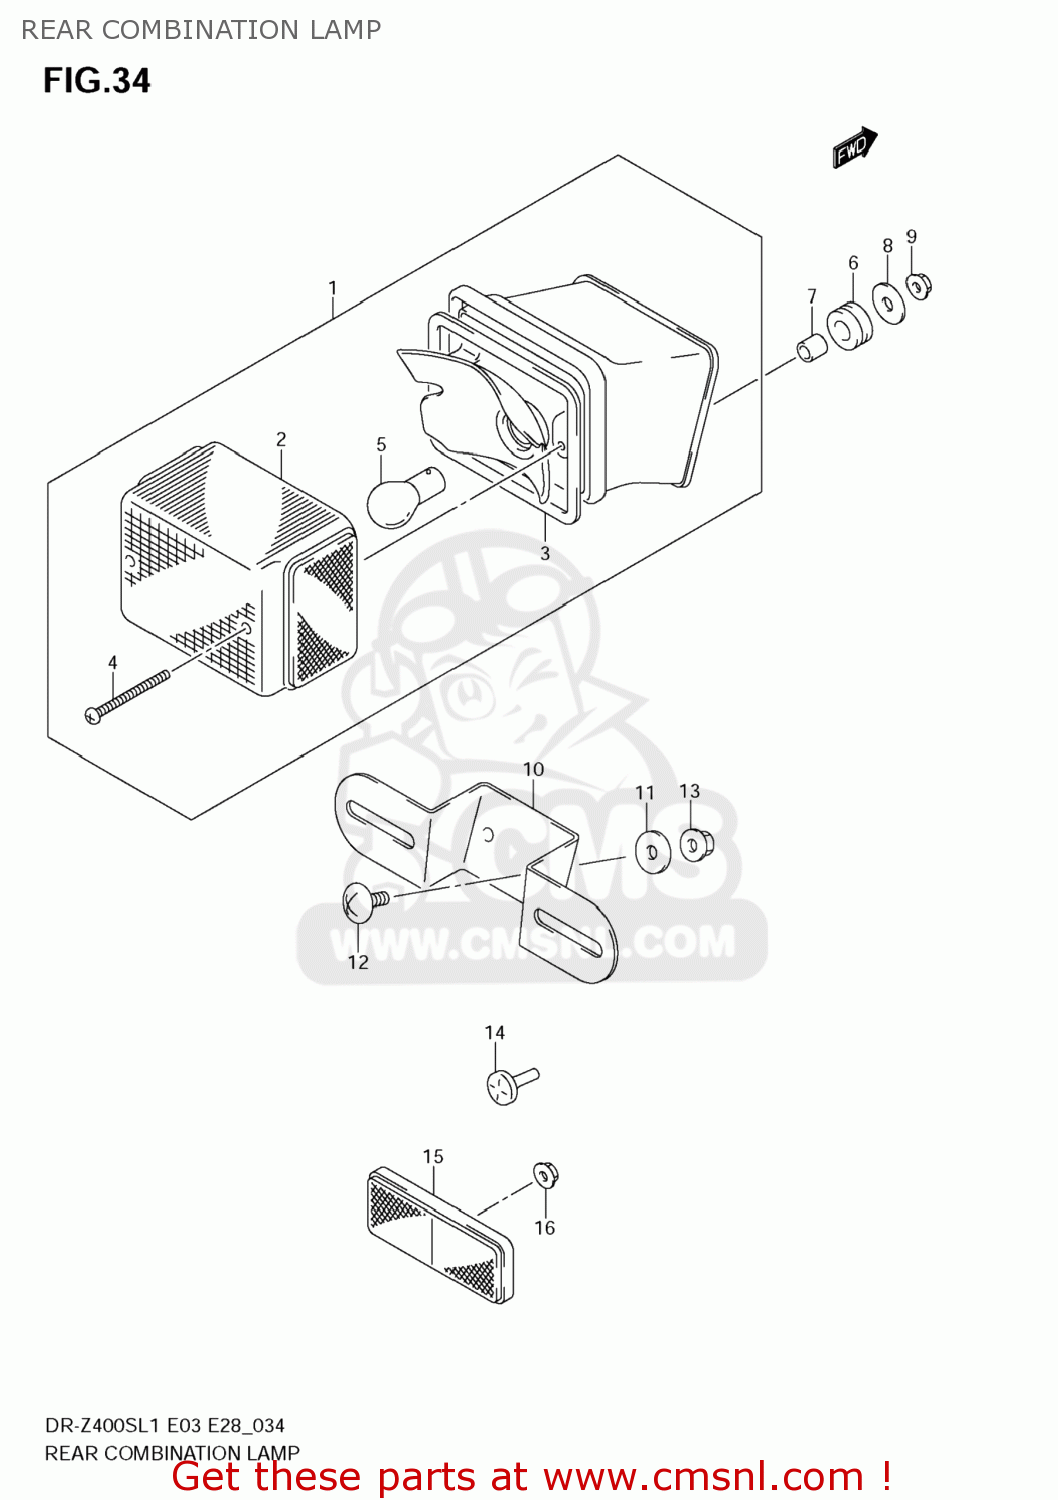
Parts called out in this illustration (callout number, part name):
1	LAMP ASSY,RR COMBINATION
2	LENS
3	GASKET,LENS (NAS)
4	SCREW(4X45)
5	BULB(12V21/5W)
6	CUSHION
7	SPACER(6.5X10X10)
8	WASHER(6.5X20X1.6)
9	NUT
10	BRACKET,LICENSE PLATE
11	WASHER(6.5X20X1.6)
12	SCREW
13	NUT
14	CUSHION
15	REFLECTOR ASSY,RR
16	NUT
